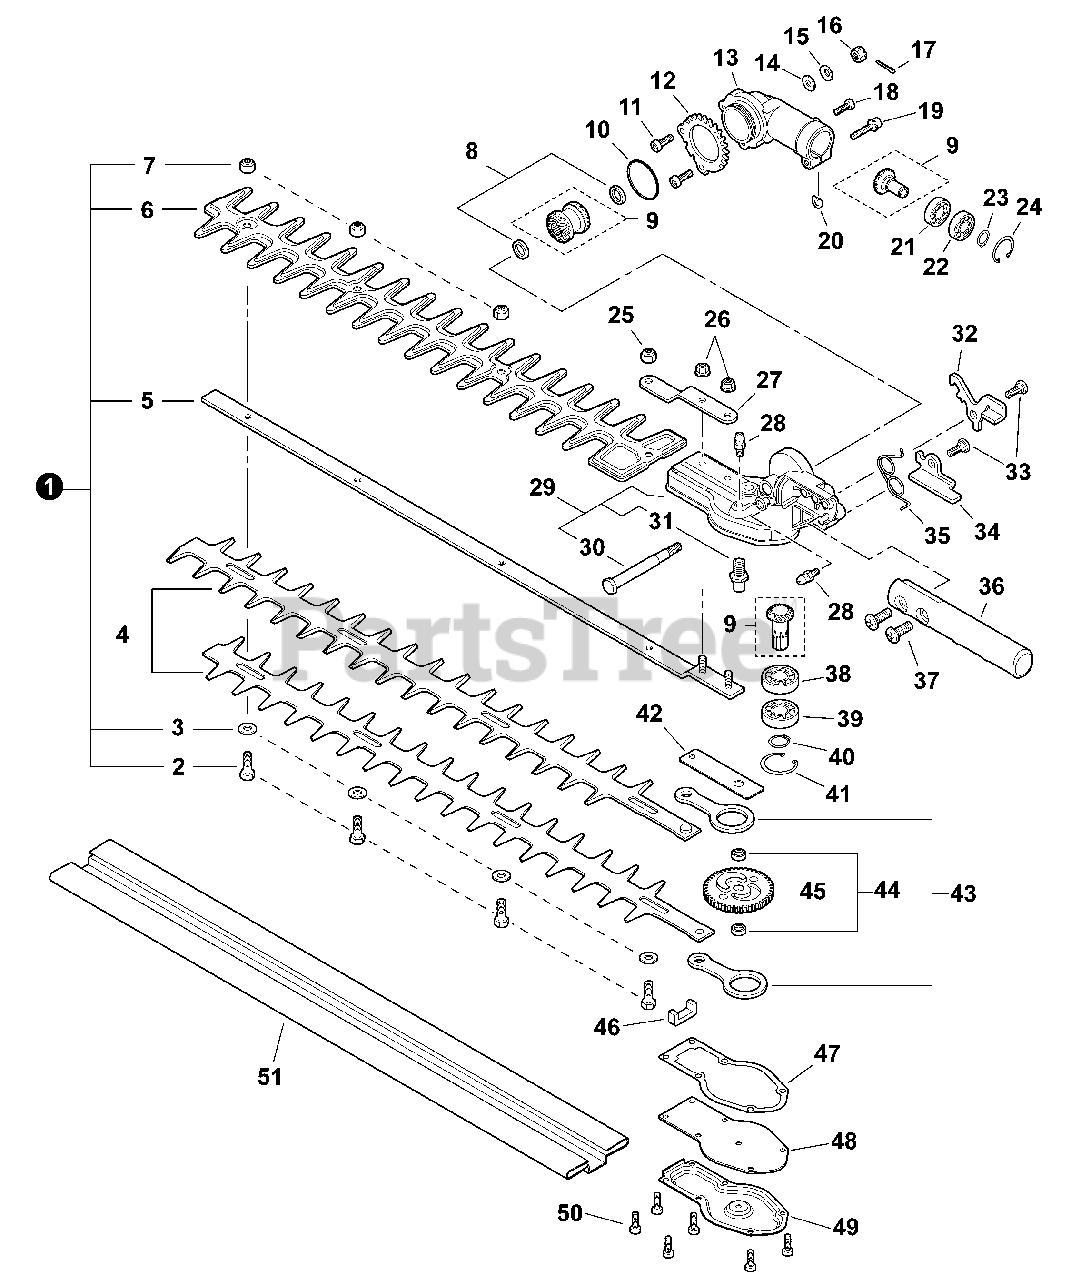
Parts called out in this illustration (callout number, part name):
1	CUTTER ASSY, 22"
2	BOLT M6×20
3	WASHER M6
4	CUTTER 22"
5	GUIDE BAR 22"
6	GUARD, CUTTER BLADE
8	COLLAR Ø16ר10×L= 2
9	GEAR SET
11	BOLT 5×12
12	RING, LOCKING
13	HOUSING, UPPER GEAR CASE
14	WASHER 6.5×13×1
15	WASHER, CONE M6
17	PIN, COTTER Ø1.6×15
18	BOLT 5×12
19	BOLT M5×25
20	D-WASHER
21	BEARING, BALL 609
22	BEARING, BALL 609ZZ
23	RING, SNAP Ø9
24	RING, SNAP Ø24
26	NUT, FLANGE M5
27	BRACKET, CUTTER
28	FITTING, GREASE
29	GEAR CASE HOUSING ASSY
31	MAINSHAFT
32	LEVER, LOCK
33	BOLT M6
34	RELEASE, LOCK
35	SPRING, TORSION
36	LEVER, ADJUSTMENT
37	SCREW, TRUSS M6×20
38	BEARING, BALL 6001
39	BEARING, BALL 6001ZZ
40	RING, SNAP Ø12
41	RING, SNAP Ø28
42	PLATE, GUIDE
44	SPACER Ø11ר8×3.4
45	GEAR, CAM
46	PACKING, FELT
47	GASKET, GEAR CASE
49	COVER, GEAR CASE
50	BOLT 4×10
51	SCABBARD
